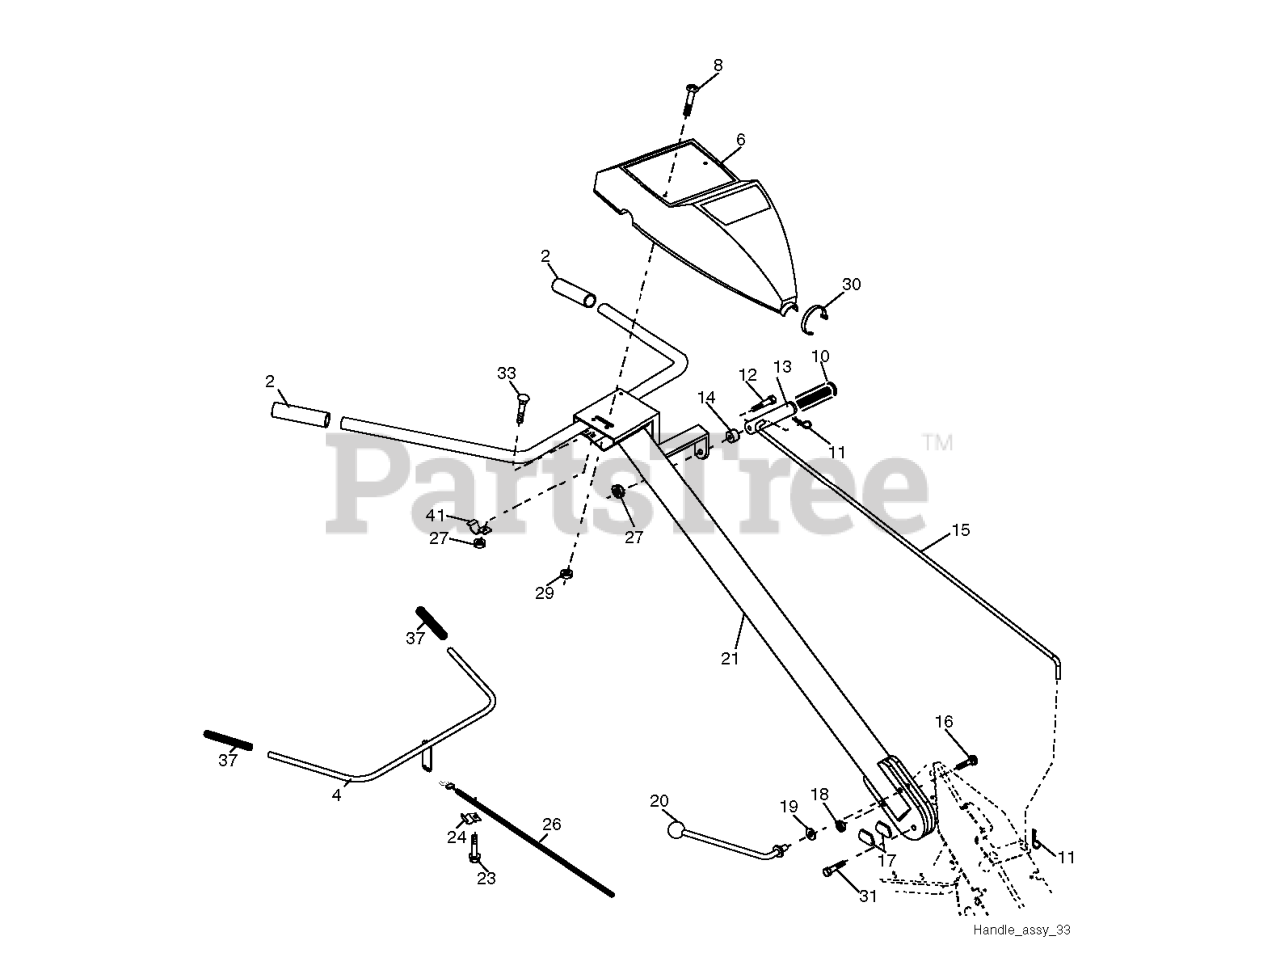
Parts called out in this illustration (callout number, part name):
2	KIT.GRIP.HANDLE.5.00.BLK.VINYL
4	CONTROL BAR ASSY
6	RP PANEL, CONTROL
8	SCREW.PNHD.10-24
10	GRIP T
11	RETAINER M
12	SHOULDER BOLT ST
13	HANDLE.SHIFT.TILLER
14	GROMMET.RUBBER.CRT.TILLER
15	SHIFT ROD CRT
16	BOLT D
17	LOCK.HANDLE.CRT
19	WASHER CRT
20	LEVER.LOCK.CRT
21	REPL BY 532 1805-17
23	TAPPING SCREW
24	CONDUIT.CLIP.PLATED
26	CABLE.CLUTCH
27	NUT T
29	NUT **
30	TIE CABLE CRT
31	BOLT.PIVOT
37	GRIP BAR CRT(1)
41	CLAMP.BAR.CRT.BLACK
